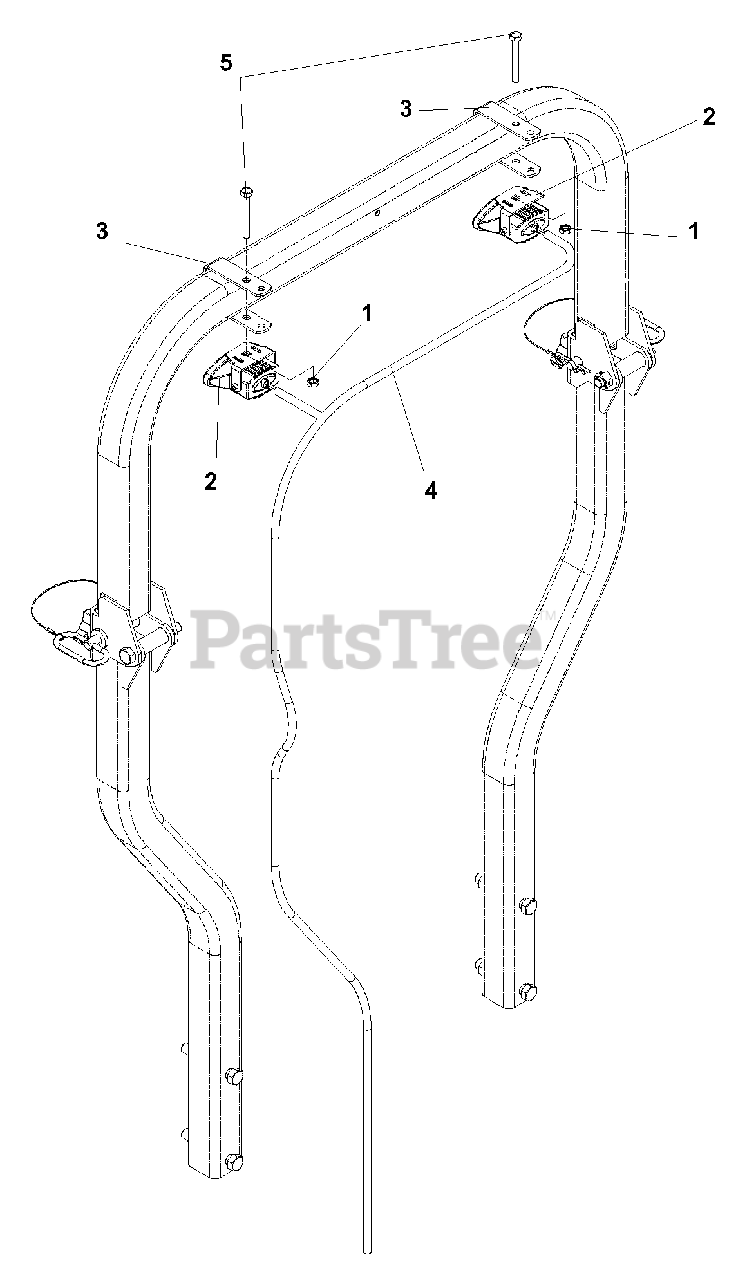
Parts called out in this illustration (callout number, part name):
1	NUT, 5/16 -18, JAM
2	LIGHT W/BRKT & HARDWARE
3	LIGHT MOUNTING BRACKET
4	LIGHT HARNESS
5	HCS, 5/16 -18 x 2 1/2, GR5
